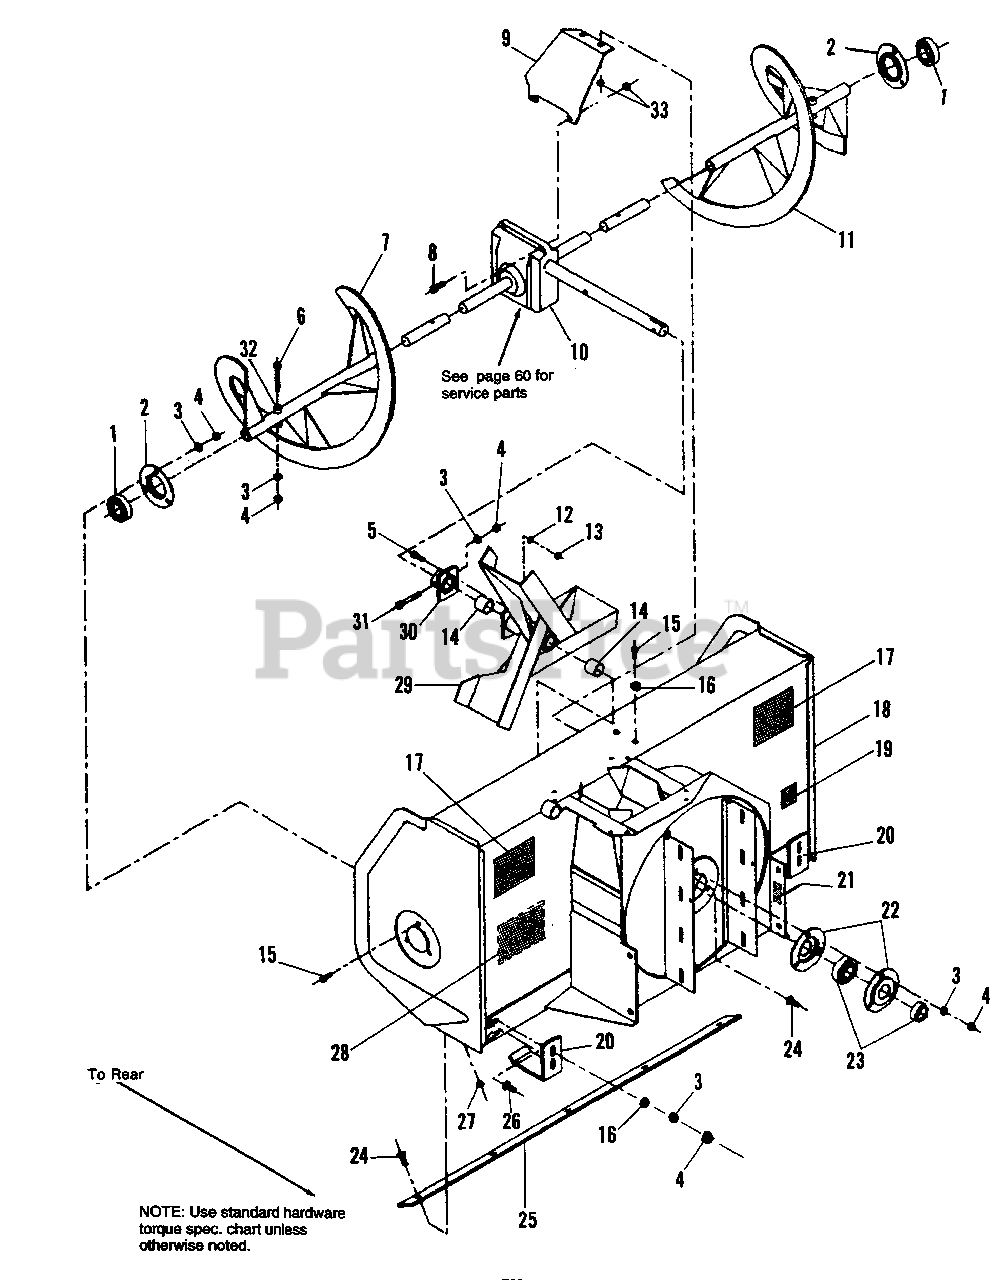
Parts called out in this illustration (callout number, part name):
1	BEARING, w/Locking Screw
2	FLANGE, Bearing
3	LOCKWASHER, 5/16
4	NUT, Hex, 5/16-18
5	BOLT, Shear, 1/4-20 x 1-1/4, Gr. 5
6	SHEAR BOLT, 5/16-18 x 2-1/4
7	AUGER ASSY., L.H.
8	CAPSCREW, Hex Hd., 5/16-18 x 1-1/4
9	BRACKET, Support
10	GEAR ASSY., Worm (Clockwise)
11	AUGER ASSY., R.H.
12	LOCKWASHER
13	NUT, Hex, 1/4-20
14	BUSHING, 1" O.D. x 1-1/8" O.D. x 1"
15	CAPSCREW, Hex Hd., 5/16-18 x 3/4
16	WASHER, Plain, S.A.E. 3/8
17	DECAL, Danger
18	FRAME ASSY.
19	DECAL, Lube, Chain
21	DECAL, Oil Level
22	FLANGE, Bearing
23	BEARING, Cartridge
24	BOLT, Carriage, 5/16-18 x 3/4
25	EDGE, Cutting
26	BOLT, Carriage, 5/16-18 x 1
27	NUT, Hex Fin. Jam, 5/16-18
28	DECAL, Shear Bolts
30	ADAPTOR, Fan Shear Plate
31	CAPSCREW, Hex Head 5/16-18 x 2 G5
32	BUSHING, Shear Bolt
33	NUT, Hex, ESNA, 5/16-18
